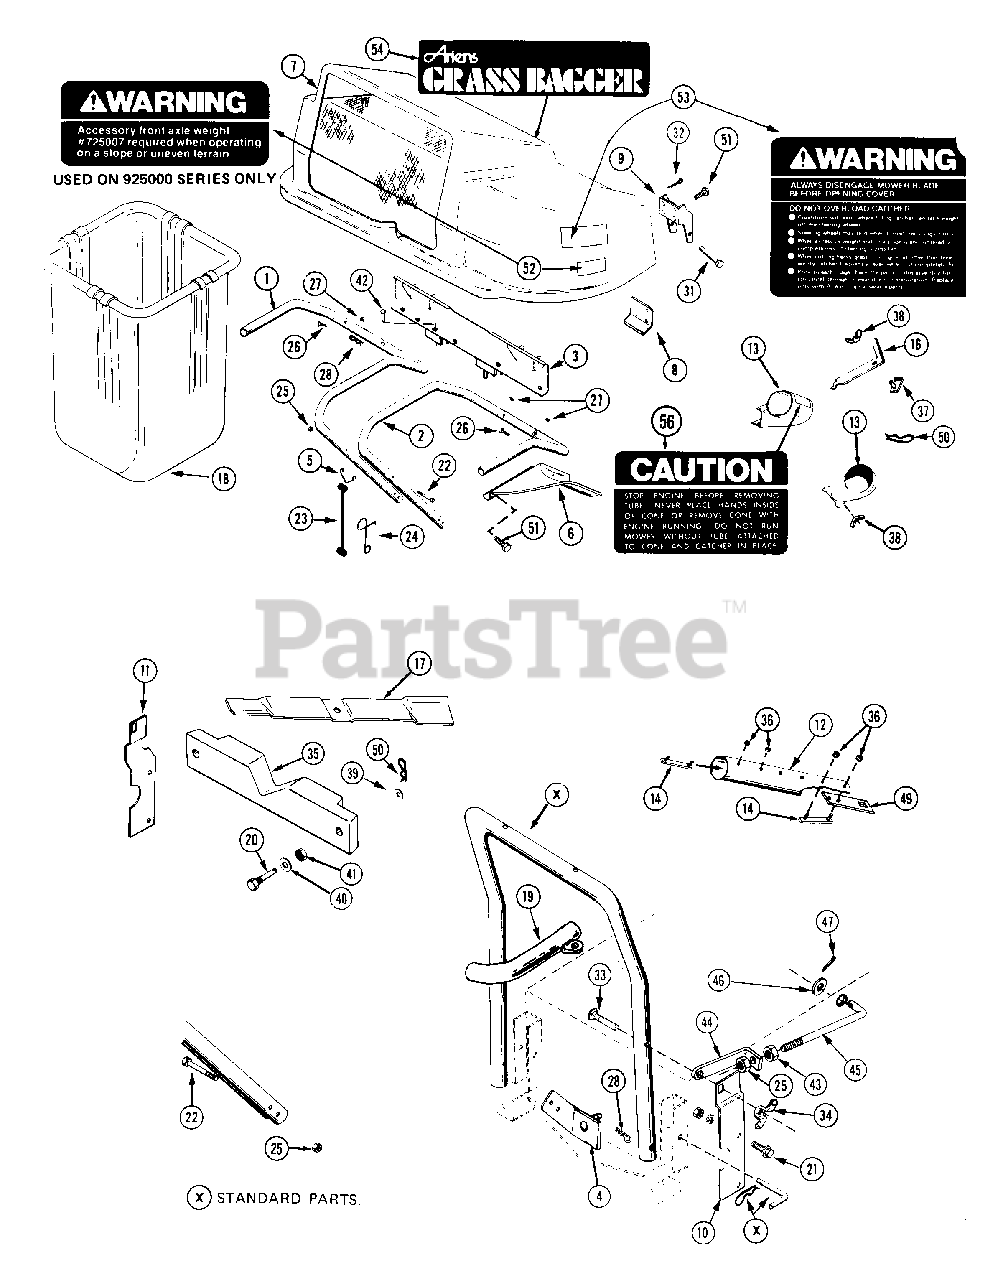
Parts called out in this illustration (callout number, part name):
1	TUBE L.H. SUPPORT
2	TUBE R.H. SUPPORT
4	LOWER MOUNTING BRACKET
6	SUPPORT
7	GRASS CATCHER COVER ASSEMBLY
8	RETAINER
10	STABILIZER R.H.
11	STABILIZER L.H.
12	TUBE BLANK
13	GRASS CATCHER BOOT ASSEMBLY
16	STRAP CONE
17	MOWER BLADE
19	EXHAUST PIPE EXTENSION
20	STUD-WEIGHT
21	BLT-SERHFWH .31-18X.50 PL
22	BLT-HEX .25-20X2.25 GR2
23	BATTERY STRAP
24	HOOK
25	NUT-LK-CTR .250-20 PL
26	SCR-MCH .31-18X1.50 CROVCNTRS
27	NUT-LK-NYL.312-18 PL
28	PIN-HAIR INT .08X.38X1.42 YWZC
31	CLEVIS PIN
32	PIN-COTR .06X.50
33	BLT-CRVD-HD .31-18X1.44 YWZC
34	WING NUT, .312-18
35	WEIGHT
36	NUT-LK-FLG .250-20 PL
37	CLIP CONE
38	NUT-WING W/INSERT .312 - 18
39	WSHR-FL-STL .438X1.0X.083 PL
40	WSHR-FL-STL .511X1.441X.125 PL
41	NUT-LK-CTR .50-13
42	CLEVIS PIN
43	NUT-HEX .250-20 PL
44	BRACKET
46	WSHR-FL-STL .265X.500X.087 PL
47	PIN-HAIR INT .08X.18X1.18
49	STRAP
50	PIN-HAIR INT .09X.188 PL
51	SCR-TAP.250-20X.62 HWH BLK ZC
52	WHEEL WEIGHT WARNING DECAL
53	WARNING DECAL
54	ARIENS GRASS BAGGER DECAL
